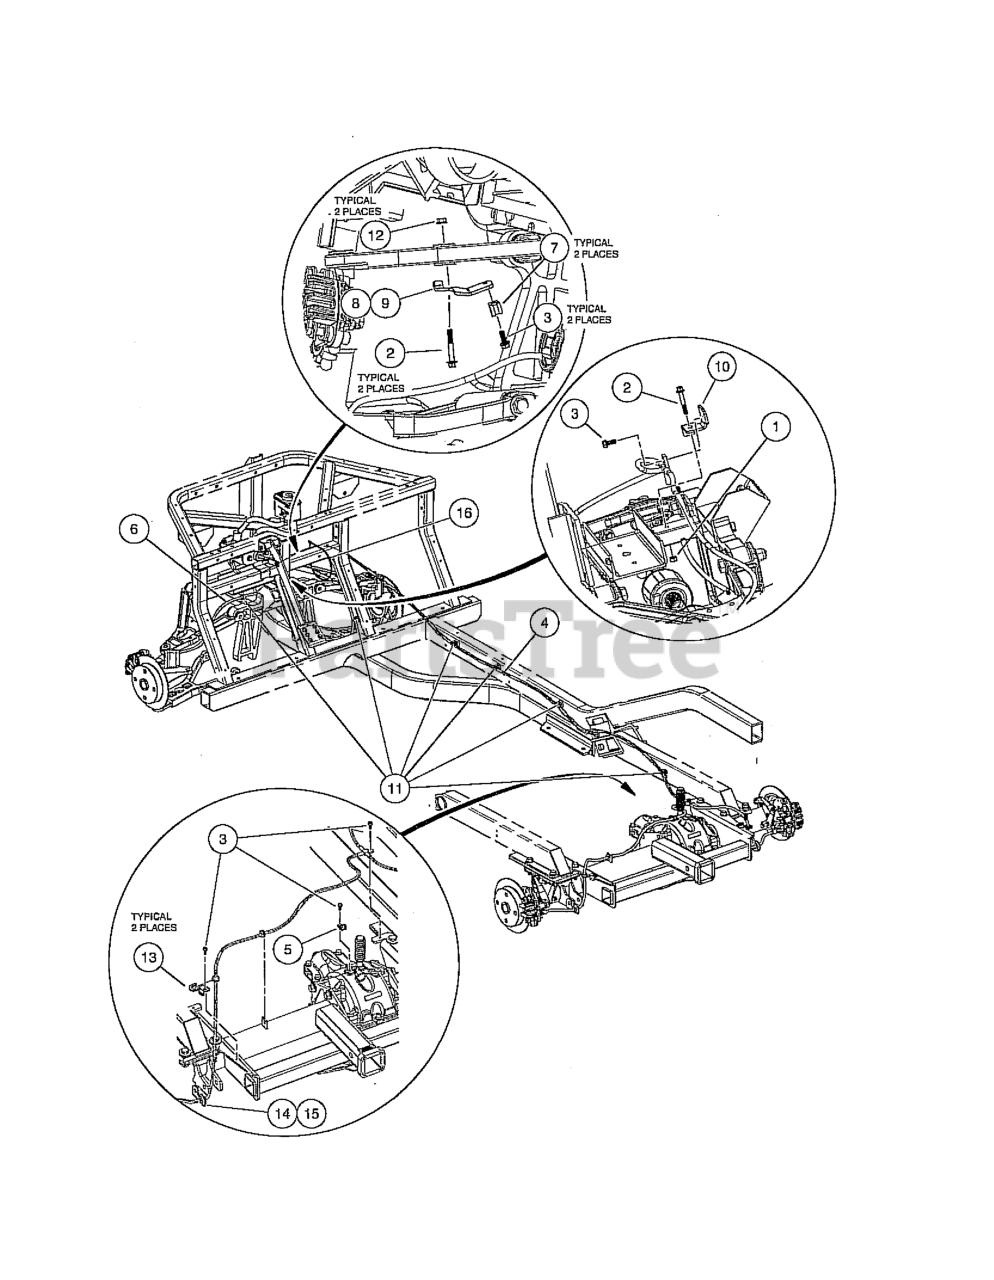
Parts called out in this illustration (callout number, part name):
1	LOCKNUT, M6-1.00 NYLON INSERT
2	BOLT - M6X1.0X40 HEX FLNG HD
3	SCREW, M6 X 16 TT HX FL HD
4	ASSEMBLY, BRAKE LINE, REAR
5	P-CLAMP, INSULATED .312 IN
6	ASSEMBLY, BRAKELINE, FRONT
7	P-CLAMP, INSULATED .312 IN
8	BRACKET, BRAKELINE, LEFT
9	BRACKET, BRAKELINE, RIGHT
10	BRACKET, TEE, BRAKELINE
11	CLIP, BRAKE LINE
13	BRKT, LINE, HYD, RECVR
14	BRKT, LINE, HYD, SHK MNT, DRV
15	BRKT, LINE, HYD, SHK MNT, PASS
16	TIE WRAP , 11" NYLON
